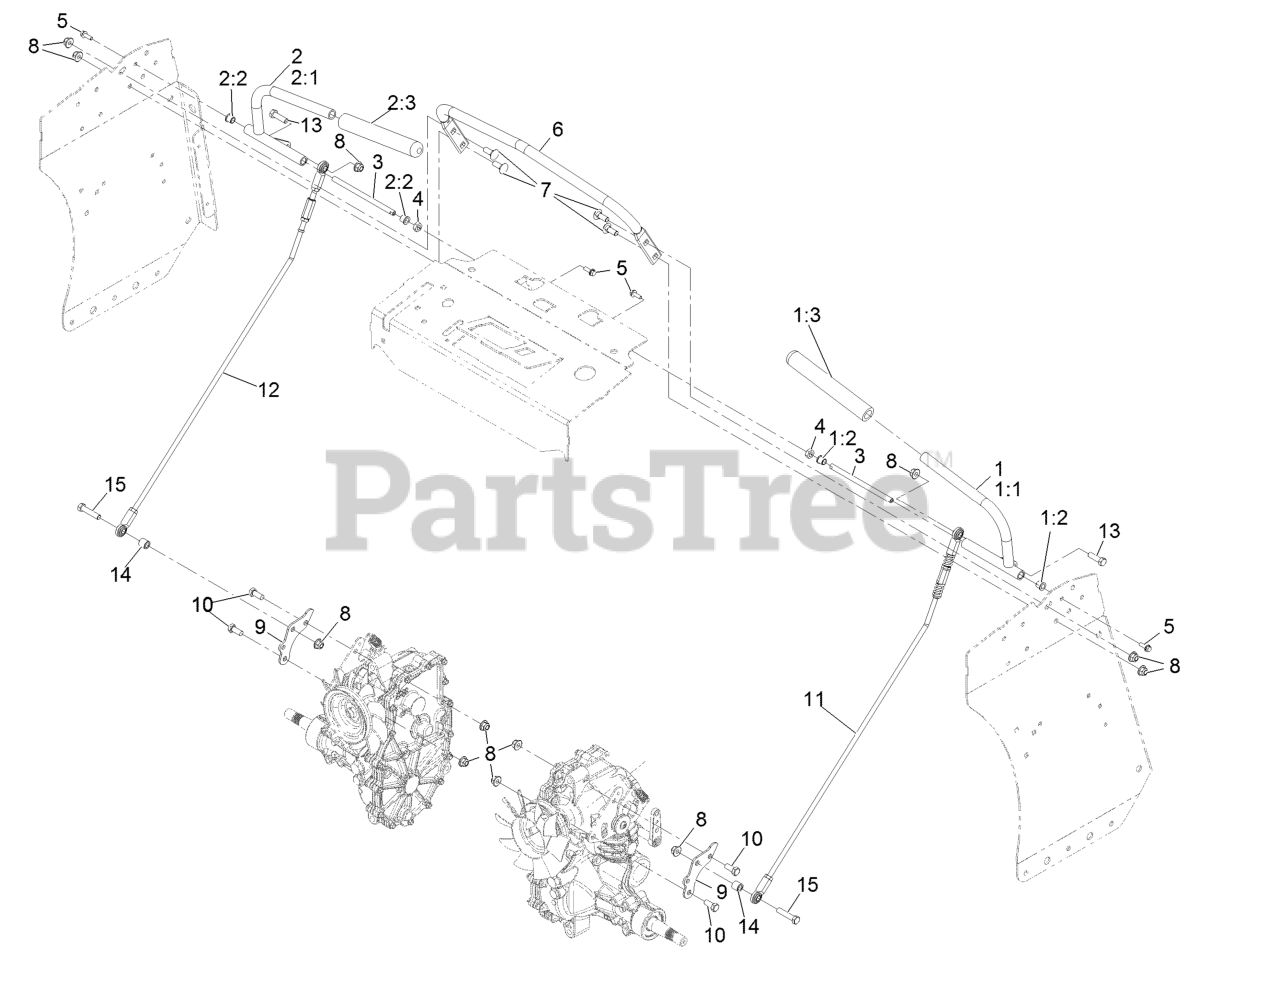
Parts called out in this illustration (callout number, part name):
1	LH Motion Handle ASM
1:1	Handle-Control, LH
1:2	Bearing
1:3	Grip-Lever, Control
2	RH Motion Handle ASM
2:1	Handle-Control, RH
2:2	Bearing
2:3	Grip-Lever, Control
3	Shaft-Pivot, Motion Control
4	Spacer-Shaft, Drive Lever
5	Screw-Hex Flange 1/4-20 X 3/4
6	Bar, Reference
7	Bolt-Carriage 3/8-16 X 1
8	Nut-Nyloc 3/8-16 Flg
9	Arm-Motion
10	Screw-HH 3/8-16 X 7/8
11	LH Motion Linkage ASM
12	RH Motion Linkage ASM
13	Screw-HH 3/8-16 X 1 1/4
15	Screw-HH 3/8-16 X 1 3/4
